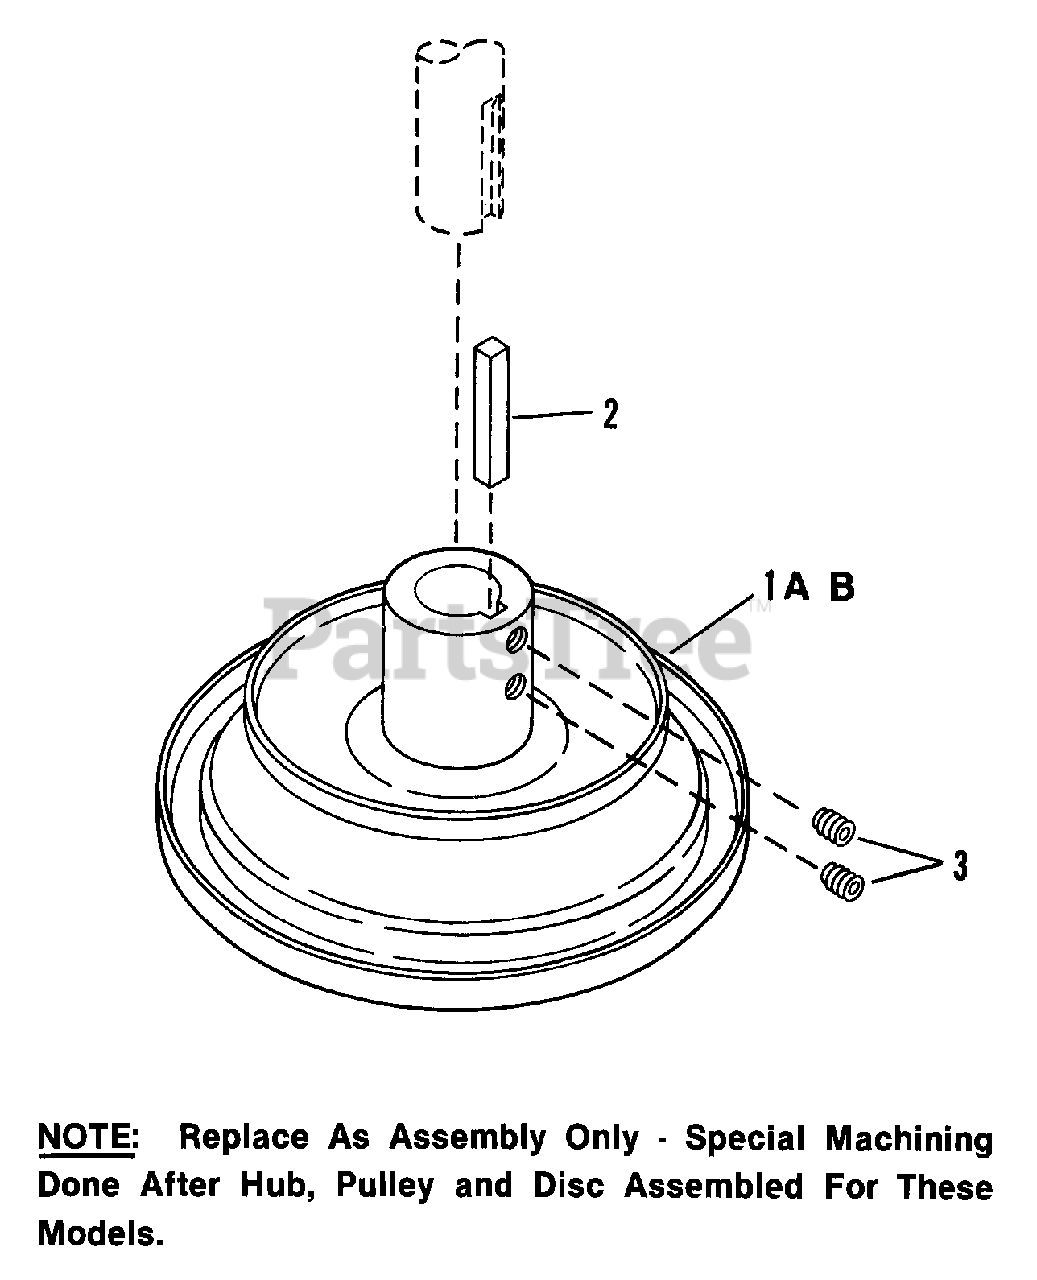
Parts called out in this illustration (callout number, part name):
1A	ASSEMBLY, Drive Disc, 4" O.D.
1B	ASSEMBLY, Drive Disc, 5" O.D.
2	KEY, 1/4x1/4x2"
3	SET-SCREW, 3/8-16x3/8"
